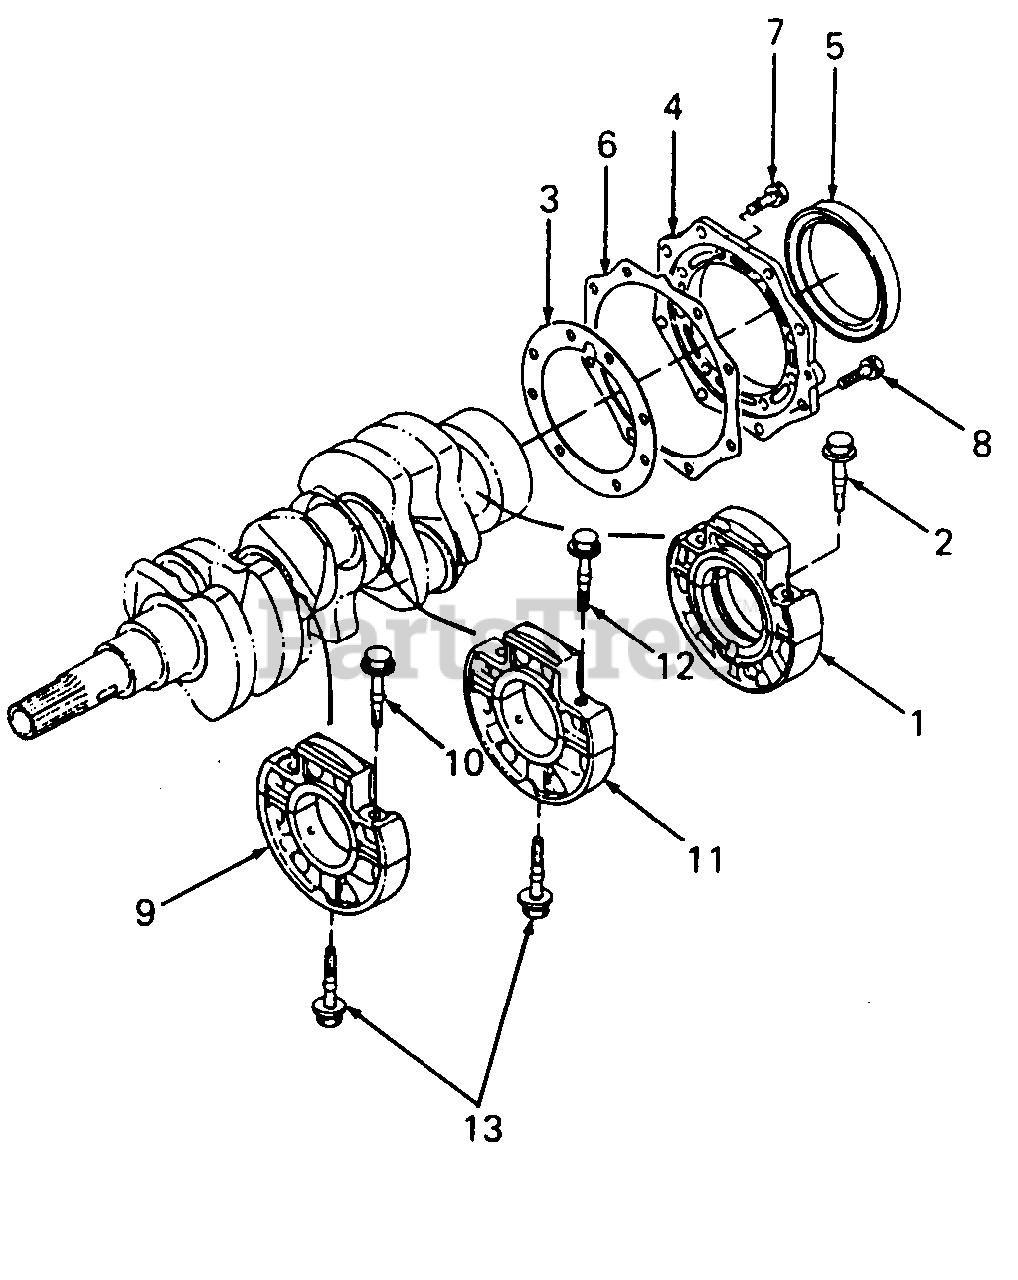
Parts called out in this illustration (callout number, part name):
1	Case, Main Bearing
2	Bolt, Bearing Case
3	Gasket, Bearing Case
4	Cover, Bearing Case
5	Seal, Oil
6	Gasket, Bearing Case Cover
9	Main Bearing Case Assy 1
10	Bolt, Bearing Case
11	Main Bearing Case Assy 2
12	Bolt, Bearing Case
13	Bolt, Bearing Case
